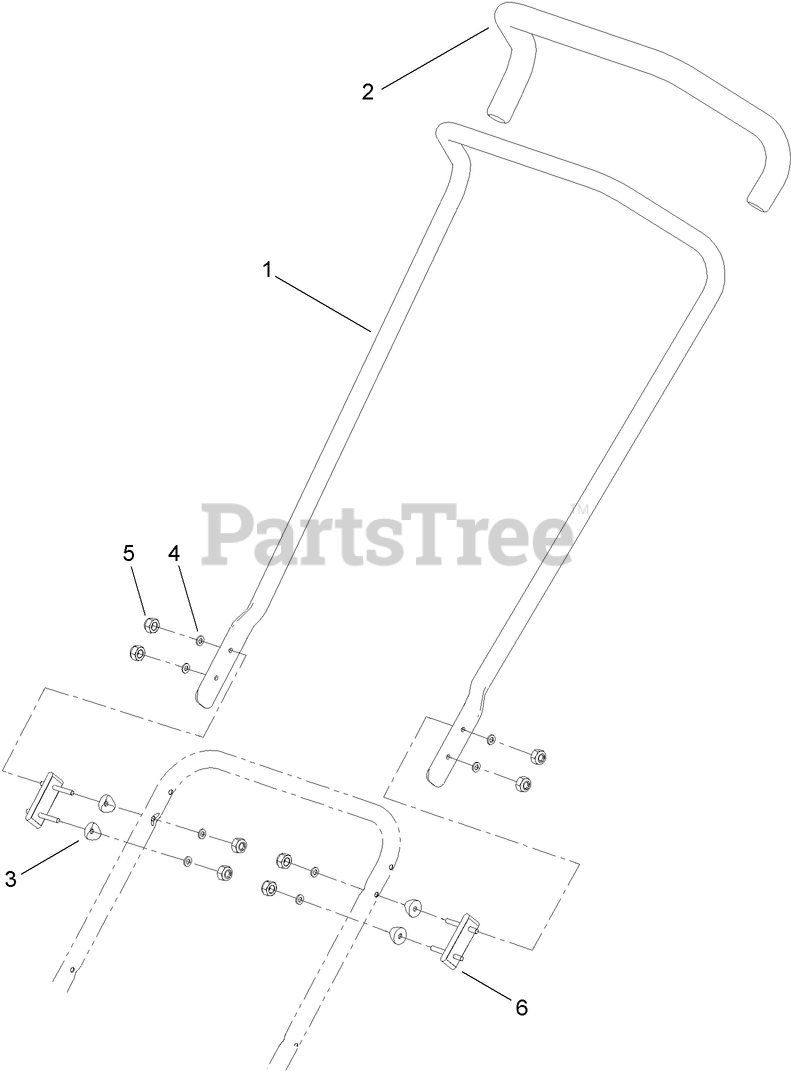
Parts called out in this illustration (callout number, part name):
1	HANDLE
2	GRIP-HANDLE
3	SADDLE
5	NUT-NYLOC
6	MOUNT-ANTI VIBRATION
